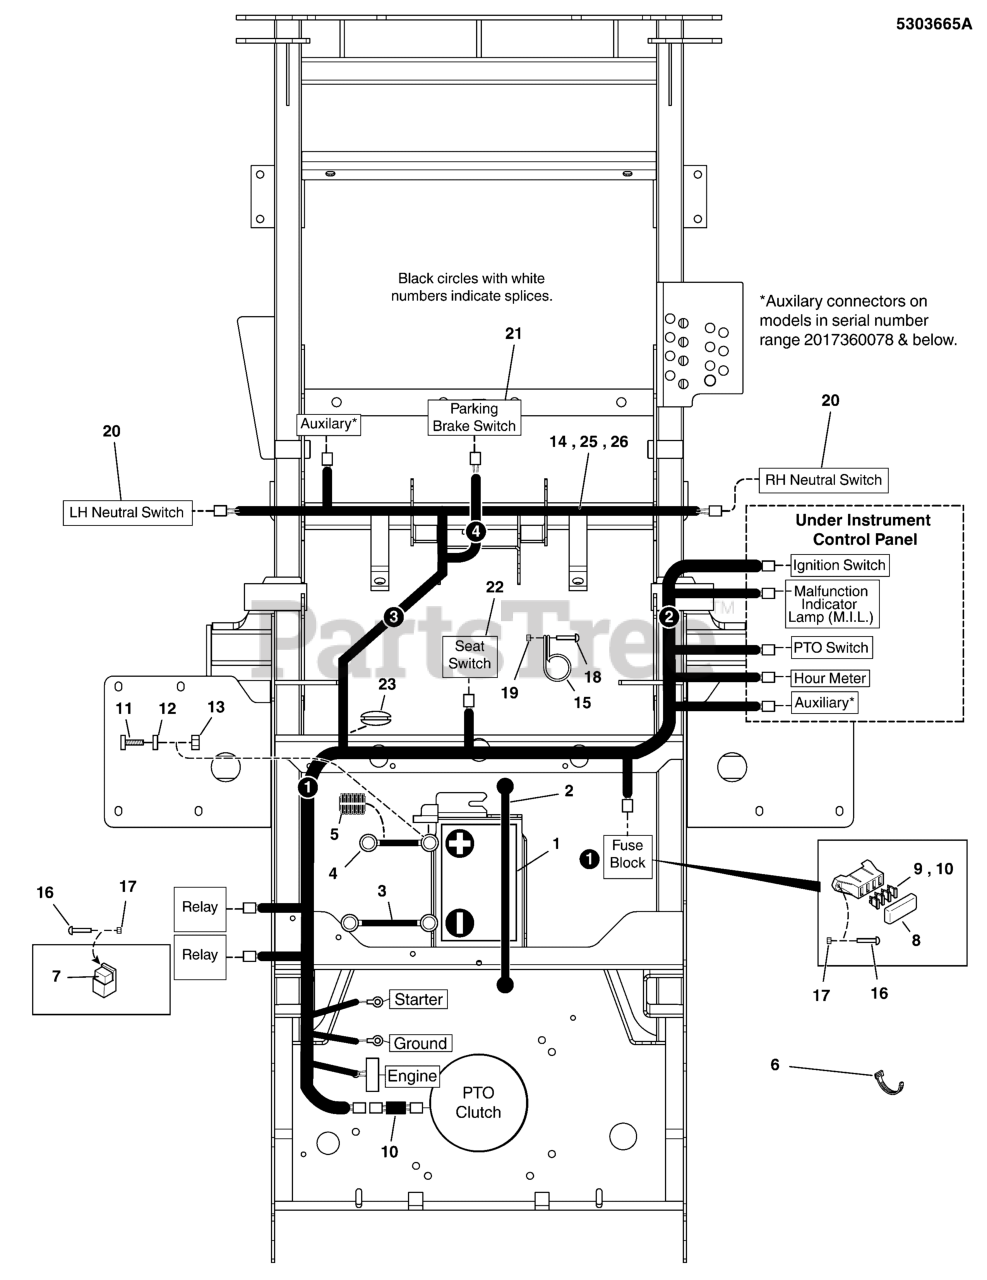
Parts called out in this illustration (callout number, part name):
1	BATTERY, WET ( BCIU1, 350 CCA)
2	STRAP-BLACK RUBB
3	BATTERY CABLE, NEG, 22, 1/4-5/16
4	BATTERY CABLE, POS, 22, 1/4-5/16
5	WIRE LOOM, 3/8 ID X 16 IN
6	TIE, SELF-LOCKING, 12"
7	RELAY, 12V, 40A
8	COVER, VINYL FUSEBLOCK
9	FUSE, ATO, 20 AMP
10	CLUTCH JUMPER W/DIODE, WARNER
11	BOLT, 1/4-20 X 3/4 GD5 YZ
12	WASHER, 1/4 SAE
13	NUT, 1/4-20 HEX SERR. FLANGE
14	WIRE HARNESS, MAIN, KOHLER 29, IS2100Z
15	CLAMP, VINYL INSULATED
16	SCREW, #10-24 X 3/4 ROUND PHILLIPS
17	NUT, #10-24 HEX NYLON LOCK
18	SCREW,1/4-20X1,ZINC PHOS & OIL
19	NUT,1/4-20,GR5,HEX,ZC/CL
20	SWITCH, PLUNGER, NO, SINGLE POLE SNAP-IN
21	SWITCH, LOW PROF, NC/NO
22	SWITCH, PLUNGER, N.C.
23	GROMMET, 1-1/2" ID FOR 1/4" METAL
24	FUSE, ATO-15 (15 AMP)
25	WIRE HARNESS, 810 OPTIMUM EFI, IS2100Z
26	WIRE HARNESS, 28HP B&S EFI, IS2100Z
